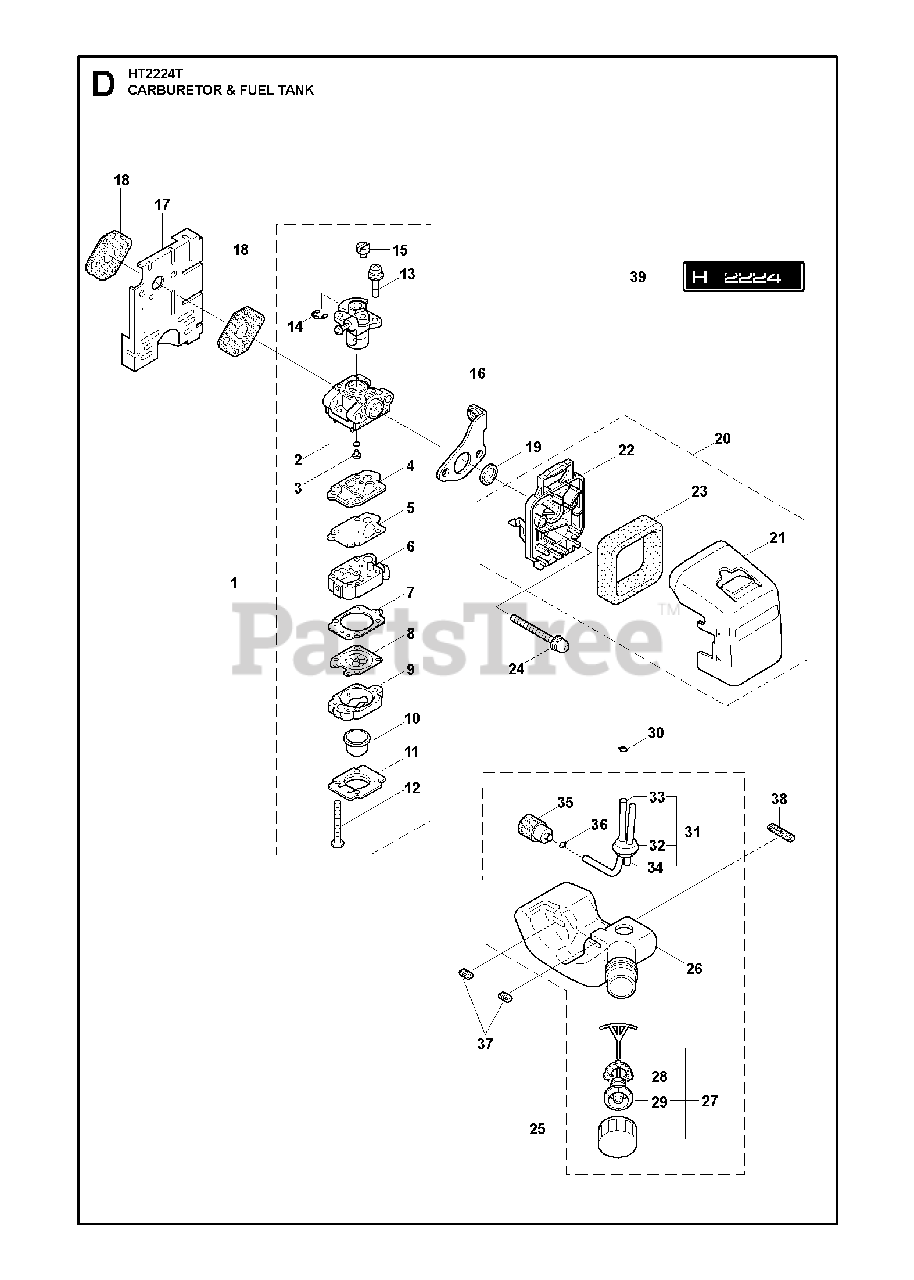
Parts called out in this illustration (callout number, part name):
1	CARBURETOR
3	JET
6	HOUSING
7	GASKET
9	HOUSING
10	PRIMER
11	PUMP COVER
12	SCREW
13	SCREW
22	FILTER COVER
23	FILTER ELEMENT
26	TANK UNIT
32	GROMMET
